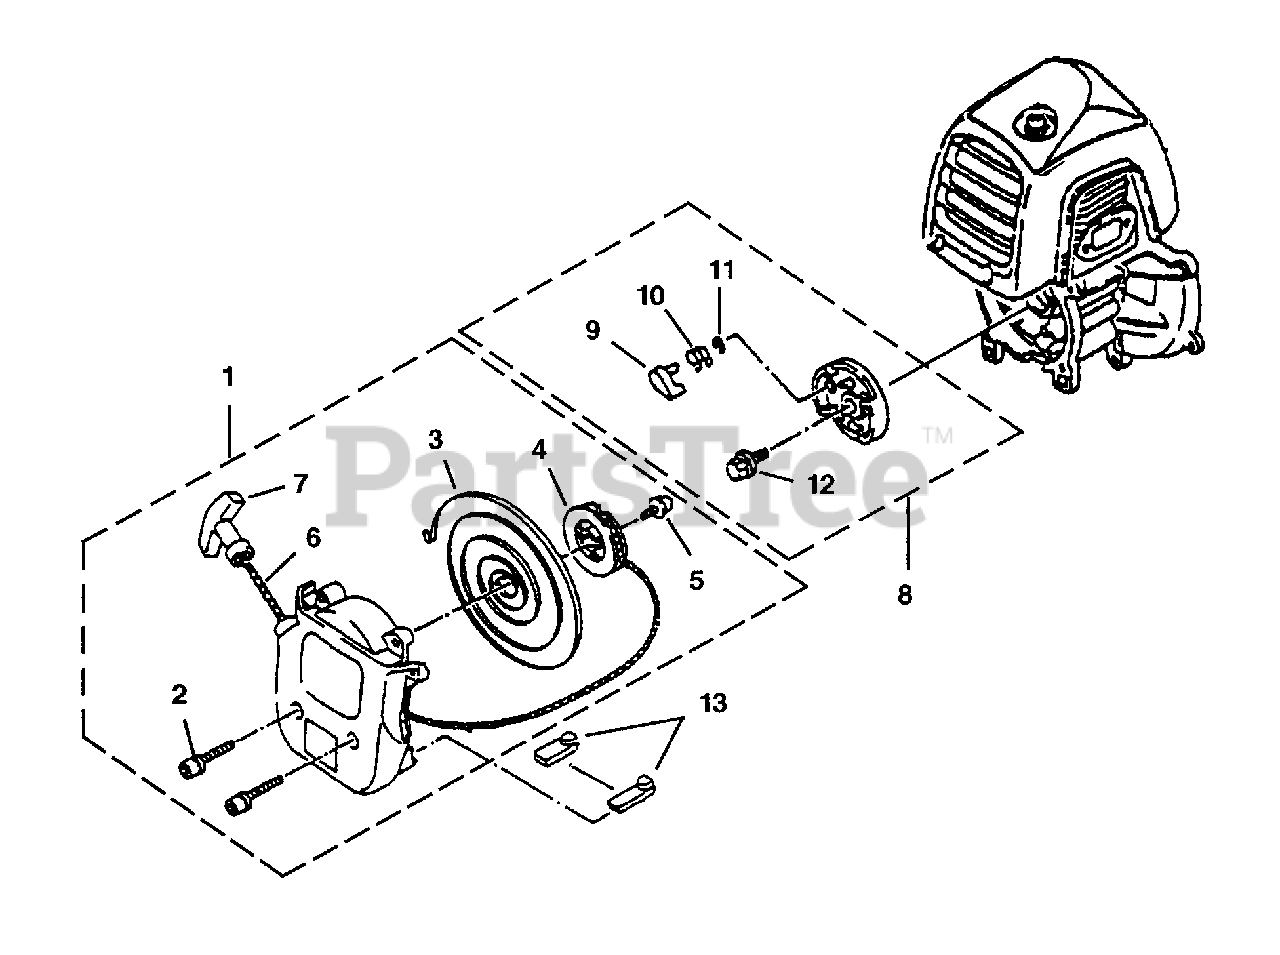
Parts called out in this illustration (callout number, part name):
1	STARTER COMPLETE
2	SCREW-Socket Hd (M5 x 30)
5	SCREW-Set (M5 x 30)
6	ROPE-Starter
8	STARTER CUP ASSEMBLY
10	SPRING-Return
12	BOLT ASSEMBLY (M6 x 14)
13	RUBBER BUMPER KIT
